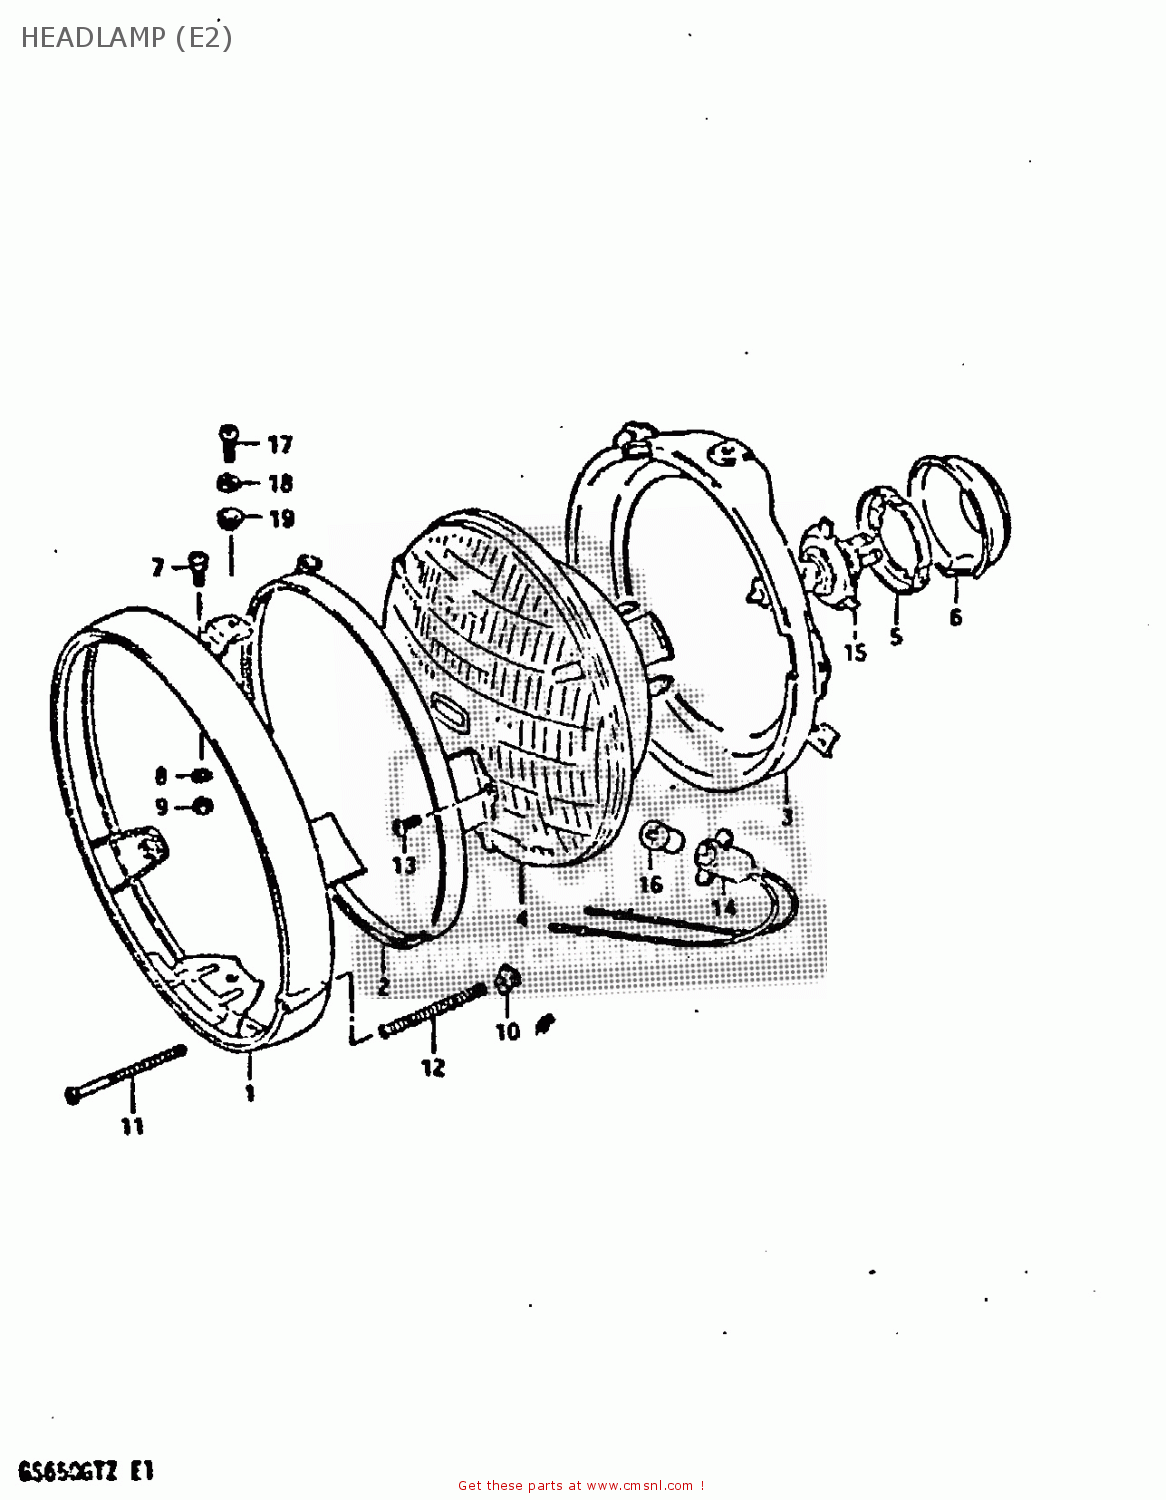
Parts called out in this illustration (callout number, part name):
1	RIM
2	RETAINING RING
3	RING
4	UNIT
5	SETTING,BULB
6	COVER,HEADLAMP SOCKET
7	H/LAMP LENS UNIT FITING SCRE
8	LOCK WASHER
9	NUT
10	NUT
11	SCREW,HEADLAMP ADJUST
12	SPRING,ADJUSTING
13	SCREW
14	SOCKET
15	BULB(12V60/55W,H4)
16	BULB
17	SCREW
18	WASHER,LOCK
19	WASHER
